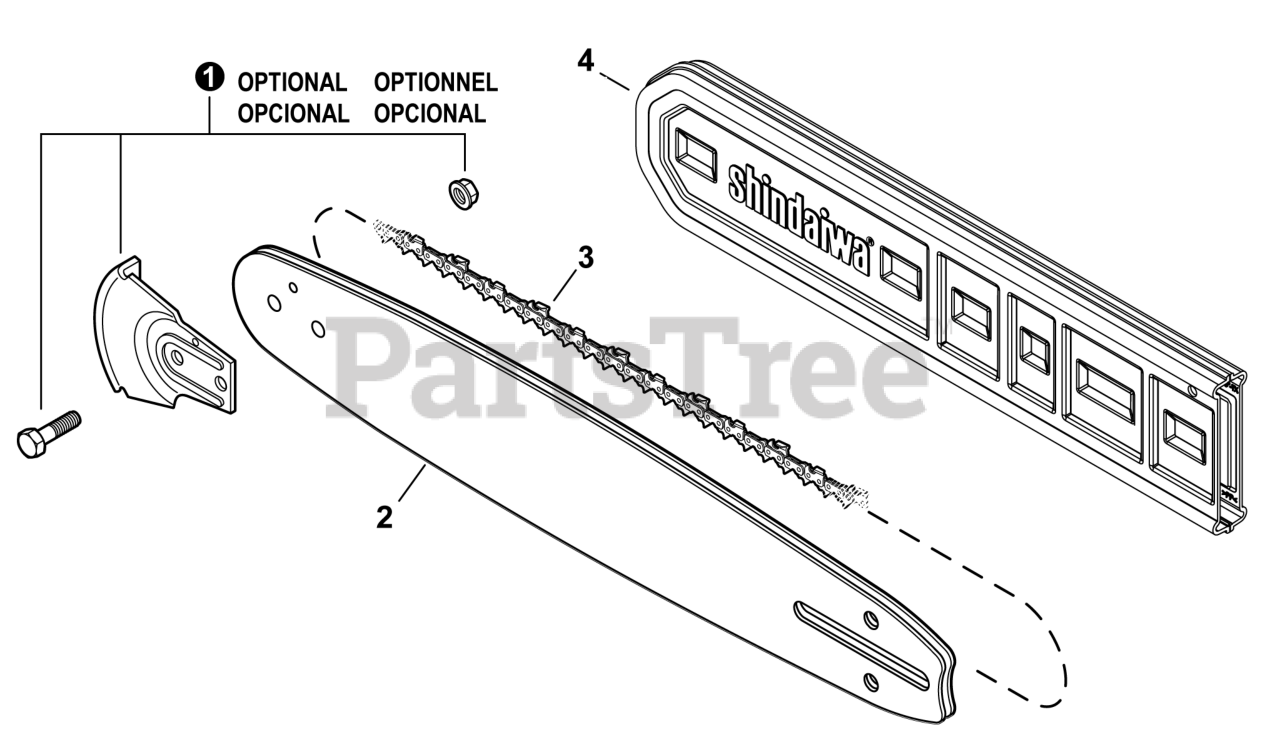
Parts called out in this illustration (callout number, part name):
1	KICK GUARD™ KIT
2	GUIDE BAR, 14" PRO-LITE
2	GUIDE BAR, 16" PRO-LITE
3	SAW CHAIN 14"
3	SAW CHAIN 16"
4	SCABBARD 14"
4	SCABBARD 16"
